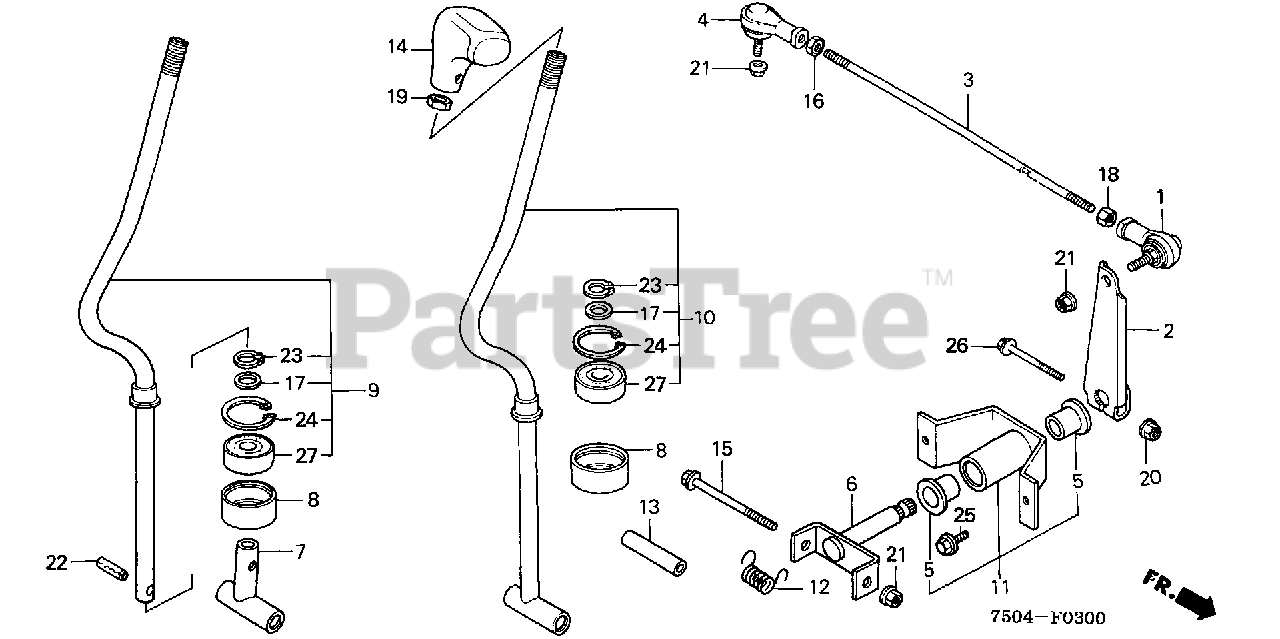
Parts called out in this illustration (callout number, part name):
1	JOINT, R. BALL
2	ARM, CHANGE (NOT AVAILABLE)
3	ROD, GEARSHIFT
4	JOINT, L. BALL
5	BUSH (15X19X22)
6	SHAFT, CHANGE LEVER (NOT AVAILABLE)
8	ROLLER, CLUTCH
10	LEVER, CHANGE (NOT AVAILABLE)
11	HOLDER, CHANGE LEVER
12	SPRING, CHANGE LEVER
13	COLLAR, CHANGE LEVER JOINT (NOT AVAILABLE)
14	KNOB, SHIFT LEVER *NH105* (MAT BLACK)
15	BOLT, FLANGE (8X68)
16	NUT, HEX. (8MM)
17	WASHER, THRUST (12MM)
18	NUT, HEX. (8MM)
19	NUT, HEX. (12MM)
20	NUT, FLANGE (6MM)
21	NUT, FLANGE (8MM)
23	CIRCLIP (OUTER) (12MM)
24	CIRCLIP (INNER) (35MM)
25	BOLT, FLANGE (6X16)
26	BOLT, FLANGE (6X35)
27	BEARING, RADIAL BALL (6202UU)
